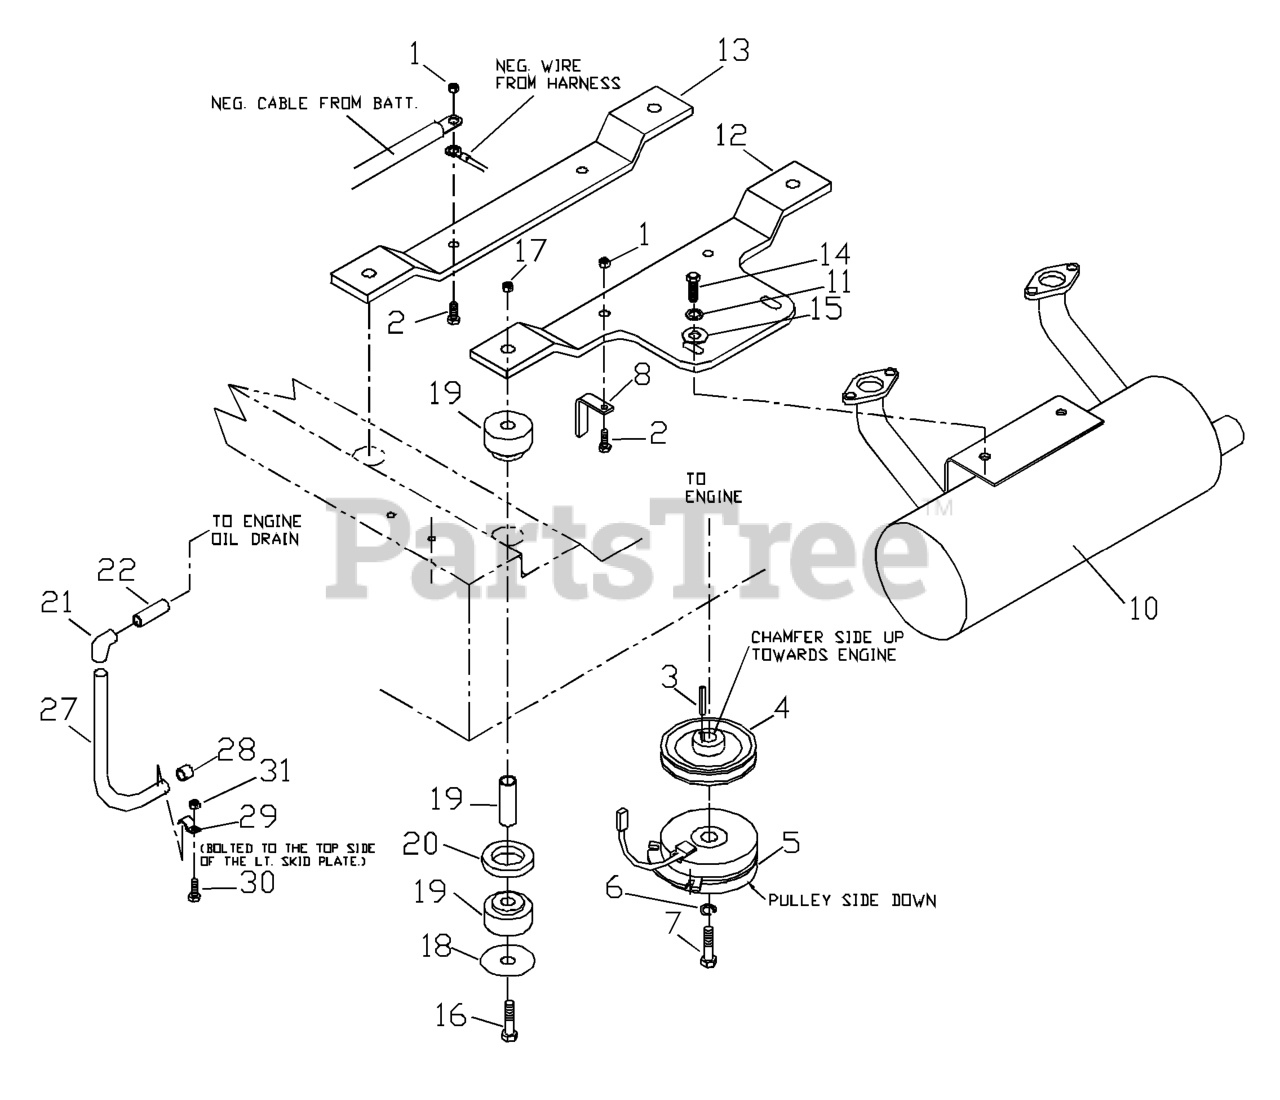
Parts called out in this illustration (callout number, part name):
1	NUT 5/16C CENTERLOCK
2	HCS 5/16C X 1 3/4
3	KEY 1/4" SQ X 1 7/8"
5	ELECTRIC CLUTCH W/CABLE
6	WASHER 7/16 LOCK
7	BOLT 7/16F X 2 1/2
8	CLUTCH TIE DOWN
10	MUFFLER KOHLER GEN II
11	WASHER.LOCK.HVY.HLCL.SPR.5/16
12	REAR ENGINE MOUNT
13	ENGINE MOUNT
14	HCS 5/16C X 3/4
15	WASHER 5/16 FLAT
16	HCS 1/2C X 3 1/4
17	NUT 1/2-13 HEX NYLOC ZD
18	ISOLATOR WASHER
20	ISOLATOR SPACER
21	90 DEG.ELBOW 3/8NPT
22	PIPE 3/8 NPT 1-1/2
27	OIL DRAIN HOSE
30	HCS 1/4C X 3/4 HCS
31	NUT 1/4C CENTER LOCK
